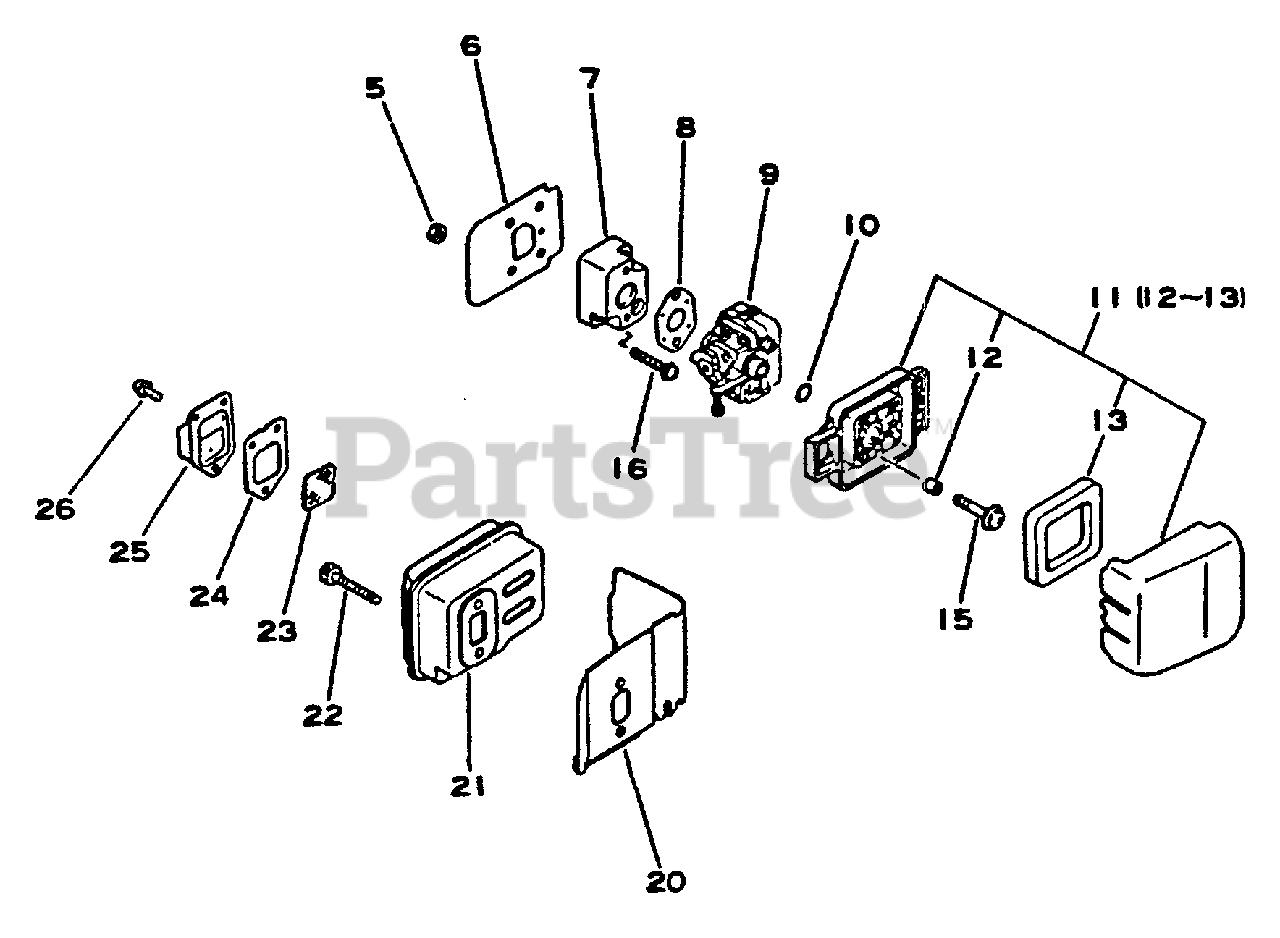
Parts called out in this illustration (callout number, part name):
6	SHIELD, INTAKE
7	INSULATOR, INTAKE
8	GASKET, INTAKE
9	CARBURETOR WYL-3
10	O-RING - 15
11	AIR CLEANER ASSY
12	SLEEVE
13	FILTER, AIR
15	SCREW - 5X64
16	SCREW - 5X20
20	GASKET, EXHAUST
21	MUFFLER
22	SCREW - 5X55
23	SCREEN, SPARK ARRESTOR
24	GASKET, EXHAUST
25	GUIDE, EXHAUST
26	SCREW - 4X10
